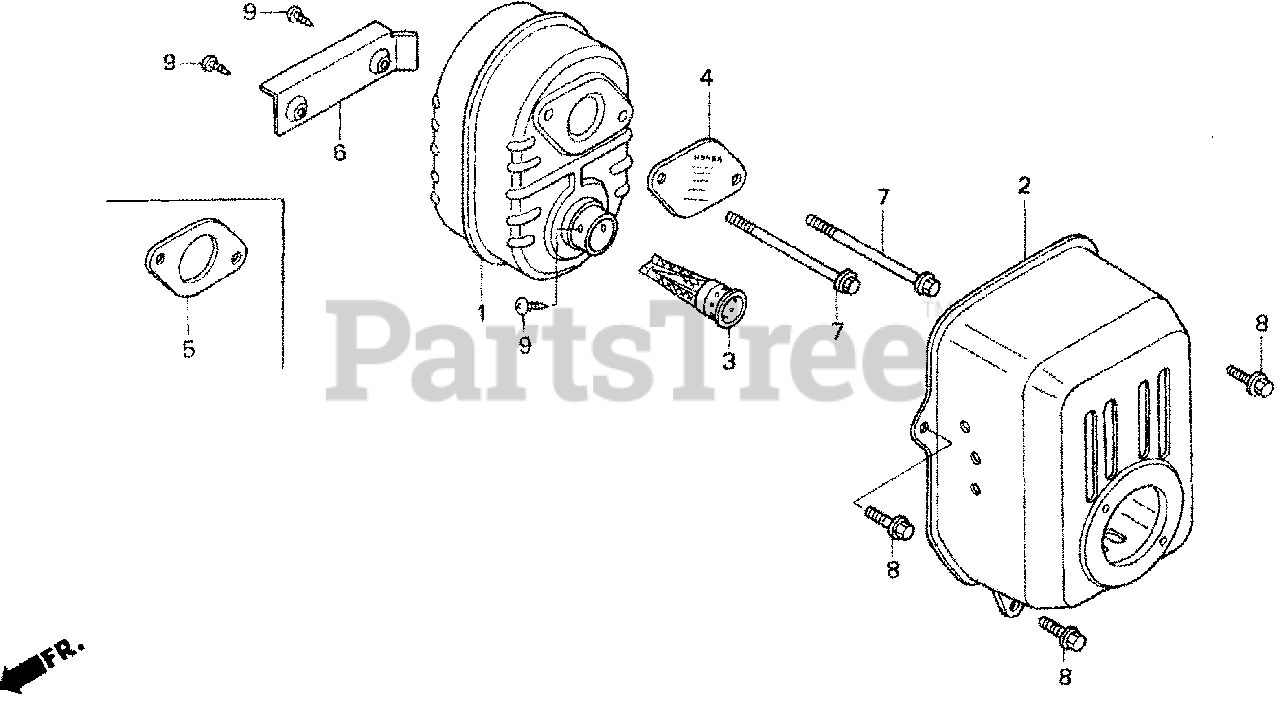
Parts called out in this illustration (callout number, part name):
2	PROTECTOR, MUFFLER
3	ARRESTER, SPARK
4	PLATE, ARRESTER NUMBER
5	GASKET, MUFFLER
6	SHROUD, MUFFLER
7	BOLT, FLANGE (6X79) (CT200)
8	BOLT, FLANGE (6X12) (CT200)
9	SCREW, TAPPING (4X6)
